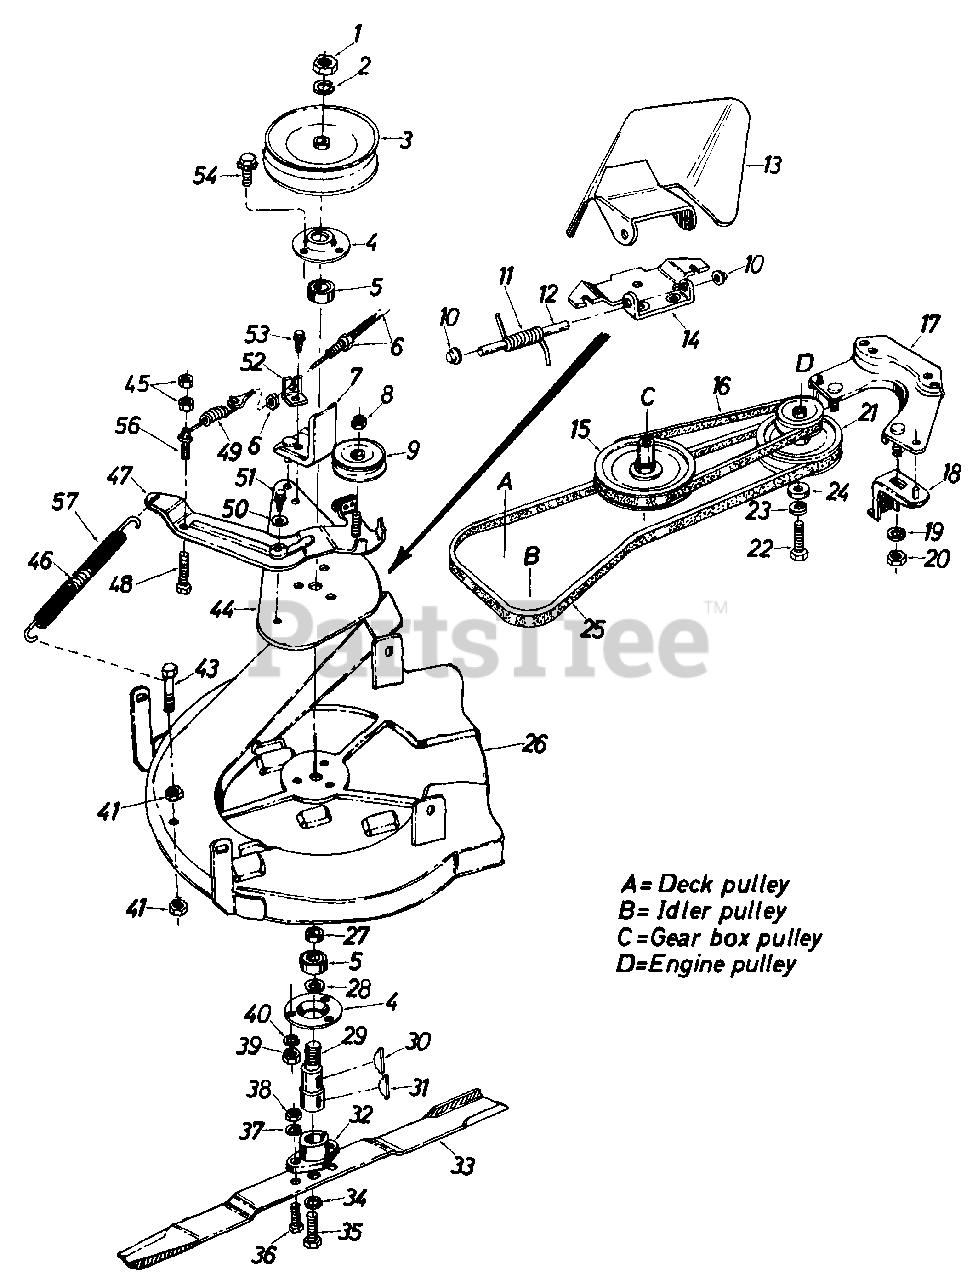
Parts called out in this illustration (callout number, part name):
1	Hex Jam Nut 5/8-11 Thd.
2	L-Wash. 5/8" I.D.
3	5/8 "V" Pulley - .63 I.D. x 7.00 O.D.
4	Bearing Housing
5	Ball Bearing
6	Blade Clutch Control Cable
7	Belt Keeper Ass'y.
8	Hex Ins. Jam L-Nut 3/8-24 Thd.
9	V-Idler Pulley
10	Push Nut 1/4 Rod
11	Torsion Spring
12	Hinge Pin
13	Chute Deflector Ass'y.
14	Adapter Plate
15	Pulley 6 1/2" Dia. (Blade Drive Belt)
16	3 V-Belt 28.0 Lg.
17	Belt Guard Cup Ass'y.
18	Belt Keeper
19	L-Wash. 5/16 I.D.
20	Hex Nut 5/16-18 Thd.
21	Two-Step Engine Pulley
22	Hex Bolt 3/8-24 x 1.00 Lg.
23	L-Wash. 3/8 I.D.
24	Fl-Wash. .38 I.D. x 1.25 O.D. x .157
25	V-Belt - A Sec. x 59.0 Lg.
26	Deck Ass'y. Comp.
27	Spacer - .84 I.D. x 1.00 O.D. x .32 Lg.
28	Fl-Wash. .793" I.D. x 1.240" O.D. x .060 Thk.
29	Blade Spindle
30	#6 Hi-Pro Key 3/16 x 5/8 Dia.
31	#6 Hi-Pro Key 5/32 x 5/8 Dia.
32	Blade Adapter Kit
33	26" Blade
34	L-Wash. 3/8" I.D. Heavy Duty
35	Hex Bolt 3/8-24 x 1.50 Lg.
36	Hex bolt 5/16-24 x 1.00 Lg.
37	L-Wash. 5/16" I.D.
38	Hex Nut 5/16-24 Thd.
39	Hex Nut 5/16-18 Thd.
40	L-Wash. 5/16" I.D.
41	Hex Cent. L-Nut 1/4-28 Thd.
43	Hex Bolt 1/4-28 x 1.50 Lg.
44	Deck Belt Guard Plate
45	Hex Cent. L-Nut 1/4-28 Thd.
46	Extension Spring .50 O.D. x 6.37 Lg.
47	Deck Idler Bracket Ass'y.
48	Hex Bolt 1/4-28 x 1.50 Lg.
49	Extension Spring .50 O.D. x 2.50 Lg.
50	Fl-Wash. .40 I.D. x .88 O.D. x .06
51	Hex Wash. Hd. Self-Tap Scr. 5/16-24 x .75 Lg.
52	Cable Support Bracket
53	Hex Wash. Hd. Self-Tap Scr. 5/16-24 x .75 Lg.
54	Hex Sems Bolt 5/16-18 x 1.0 Lg.
56	Spacer .28 I.D. x .62 O.D. x .55 Lg.
57	Shrink Tube - .50 O.D. x 5.0" Lg.
